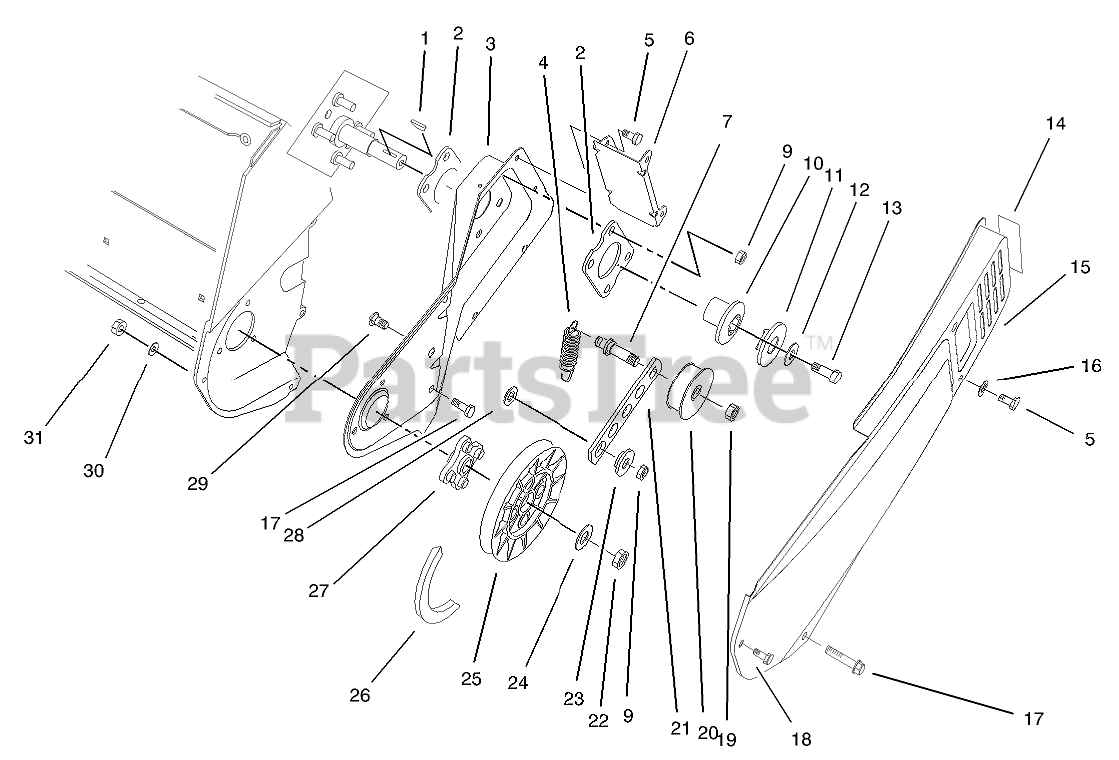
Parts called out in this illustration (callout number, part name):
1	KEY-WOODRUFF
2	PLATE-ENGINE
3	SIDEPLATE-LH
4	SPRING-EXTENSION
5	SCREW-HWH
6	BRACKET-COVER, BELT
7	PIN-IDLER
9	NUT-LOCK, NI
10	Hub-HALF SHEAVE
11	CAP-HALF SHEAVE
12	WASHER-FLAT
13	SCREW-HH
14	DECAL-WARNING
15	COVER-BELT
16	WASHER-FLAT
17	SCREW-PLASTIC
19	NUT-LOCK, NI
20	PULLEY-IDLER
21	ARM-IDLER
22	NUT-LOCK, NI
23	BUSHING-IDLER
24	WASHER-FLAT
25	PULLEY-DRIVEN
26	V-BELT
28	WASHER
29	SCREW-CARR
30	WASHER-FLAT
31	NUT-LOCK, NI
